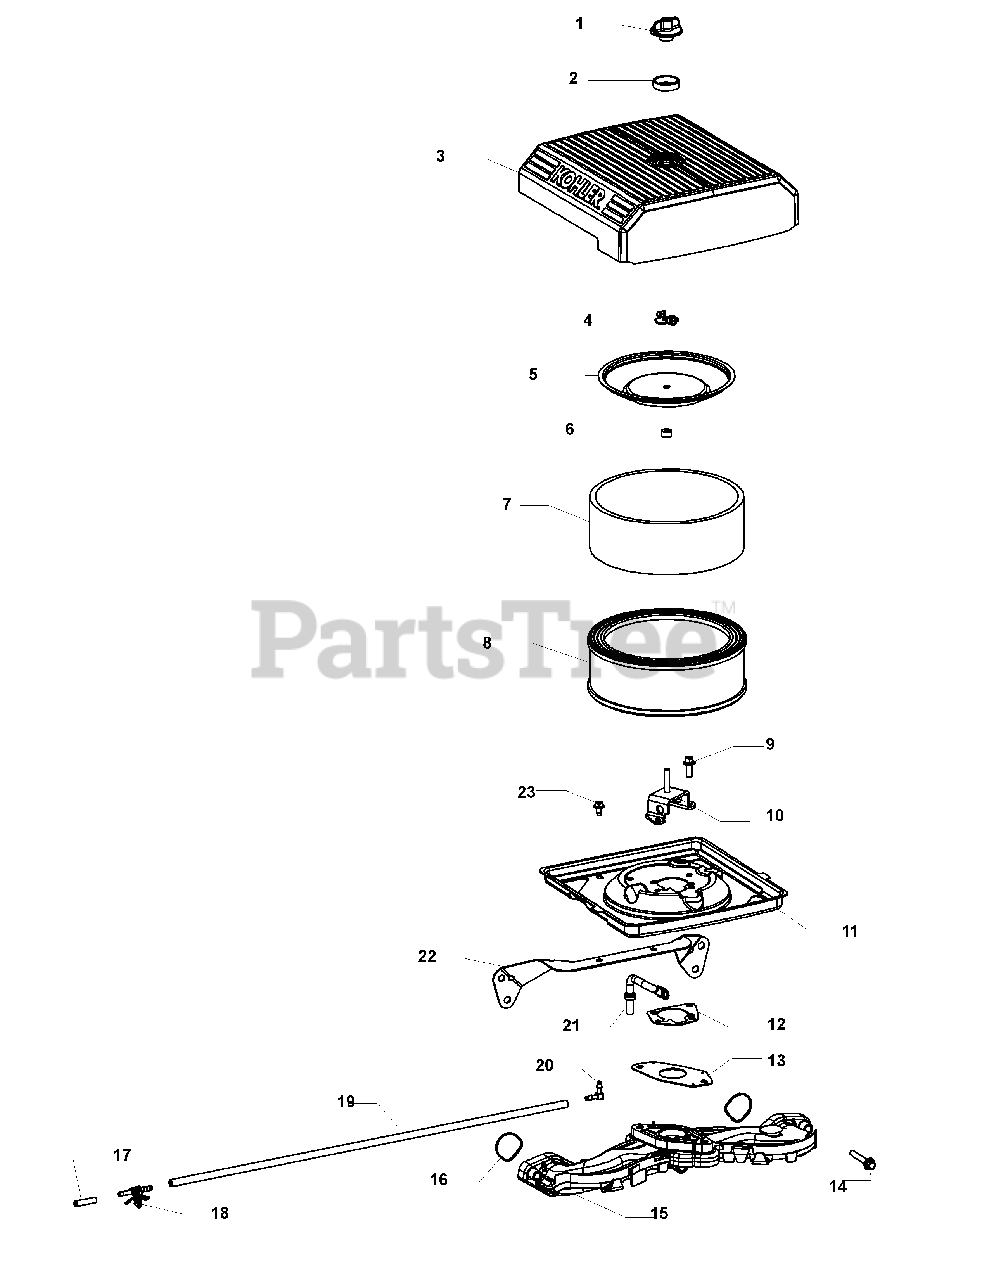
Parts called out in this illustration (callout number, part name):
3	Cover, Air Cleaner
5	Cover, Inner Air Cleaner
6	Seal, Inner Air Cleaner
7	Element, Precleaner (Low)
8	Elements, Air Cleaner Filter & Precleaner
9	Screw, Flg Thd Frm M6x1.0x16
10	Bracket, Air Cleaner
11	Kit, Air Cleaner Base
12	Gasket, Air Cleaner Base
13	Gasket, Carburetor
14	Screw, Flg M6x1.0x40
15	Kit, Intake Manifold
16	O-Ring, Intake Port
18	Connector, Evaporative
19	Hose, Evaporative, 20"
20	Connector, Evaporative Hose
21	Hose, Evaporative
22	Bracket, Air Cleaner Base
23	Screw, Flg Thd Frm M5x0.8x10
